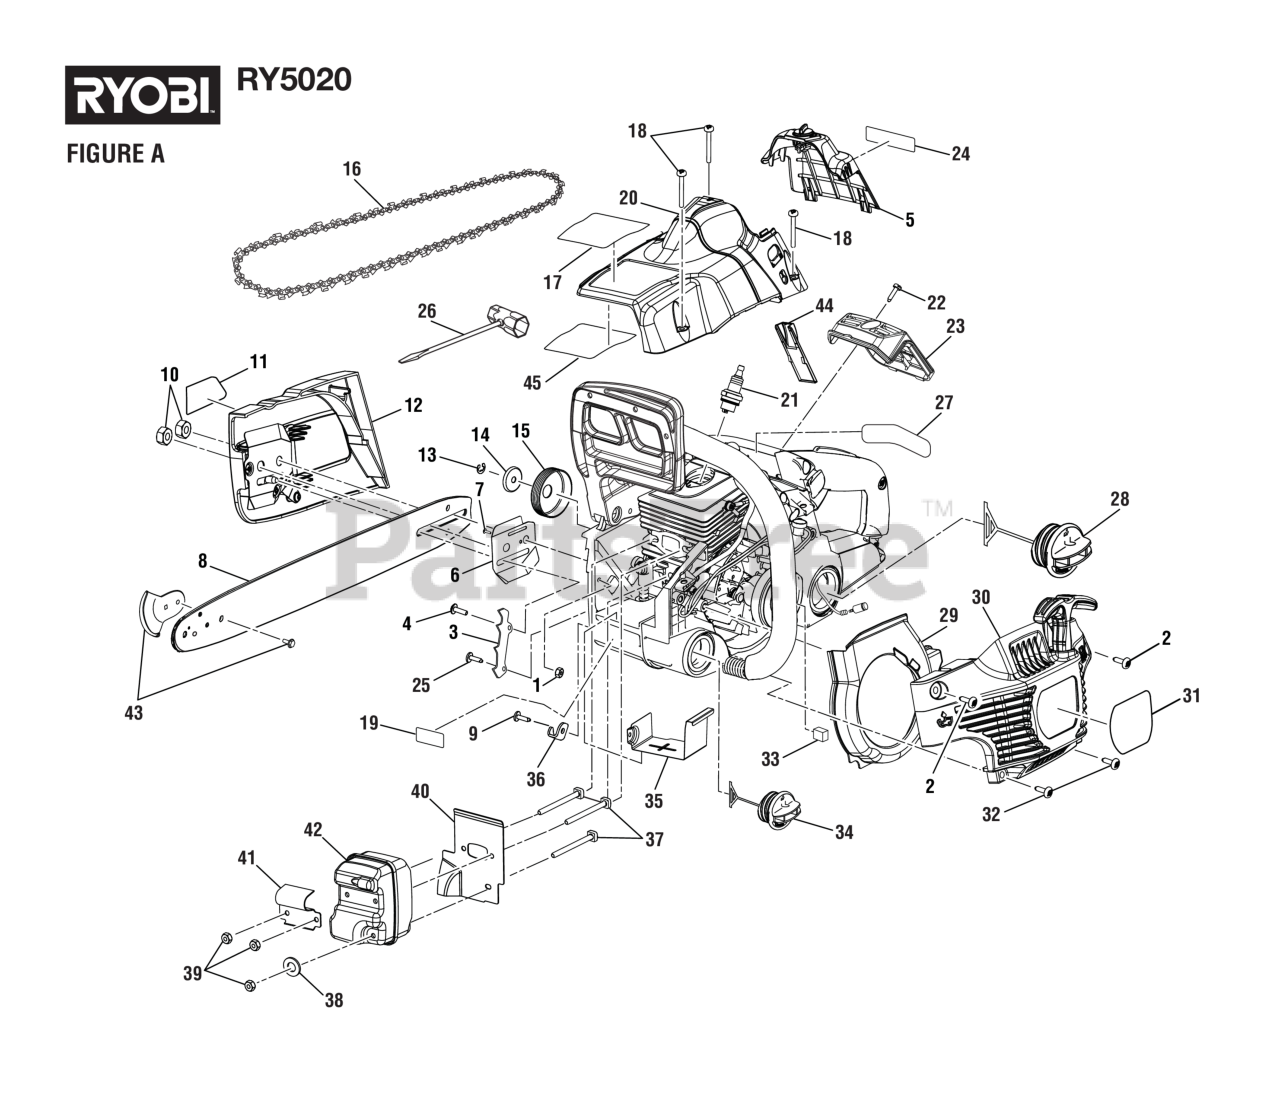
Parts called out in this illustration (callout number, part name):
1	LOCK NUT, HEX (10-24)
2	Screw, Truss Hd., Plastite (10-14 x 5/8")
3	BUMPER SPIKE
4	Screw (10-24 x 5/8 in., Torx Pan Hd.)
5	Filter Cover
6	Inner Guide Plate
7	Screw (#6-19 x 1/2 in., Phillips Hd. T.F.)
8	20 in. Guide Bar Assembly (Inc. Key No. 43)
9	Screw (10-14 x 1/2 in., Torx Truss Hd. T.F.)
10	Hex Nut (5/16-18 Flange)
11	Logo Label
12	Chain Cover Assembly
13	RING, RETAINING
14	Cupped Washer
15	Sprocket Drum and Bearing Assembly (.325 chain)
16	Chain (.325 x 78 links, 20 in.)
17	Warning Label
18	Screw (10-16 x 1-1/2 in. Special)
19	Warning Label (Combustion)
20	Cylinder Housing
21	Spark Plug (Champion RCJ6Y)
22	Screw-Slotted Pan Hd. (8-16 x 5/8")
23	Air Filter 50cc
24	Chain Replacement Label
25	Vacuum Tube Screw (10-14 x 1/2 in., T25 Torx Truss Hd. T.F.)
26	Combination Wrench
27	Starting Instruction Label
28	Fuel Cap Assembly
29	Fan Housing Baffle
30	Starter Cover Assembly
31	Logo Label (Item No. RY5020)
32	Screw, Truss Hd., Plastite (10-14 x 7/8")
33	PRE FILTER
34	Oil Cap Assembly
35	Heat Shield
36	Chain Catcher
37	Muffler Bolt (Square Hd.)
38	Washer (OD16 x ID5.5 x 1.5t)
39	NUT-LOCKING HEX (10-32)
40	Muffler Gasket
41	Muffler Deflector
42	Muffler Assembly
43	SAFE-T-TIP and Screw Assembly (.325 Bar)
44	Cylinder Housing Divider
45	Heat Reflector Tape
